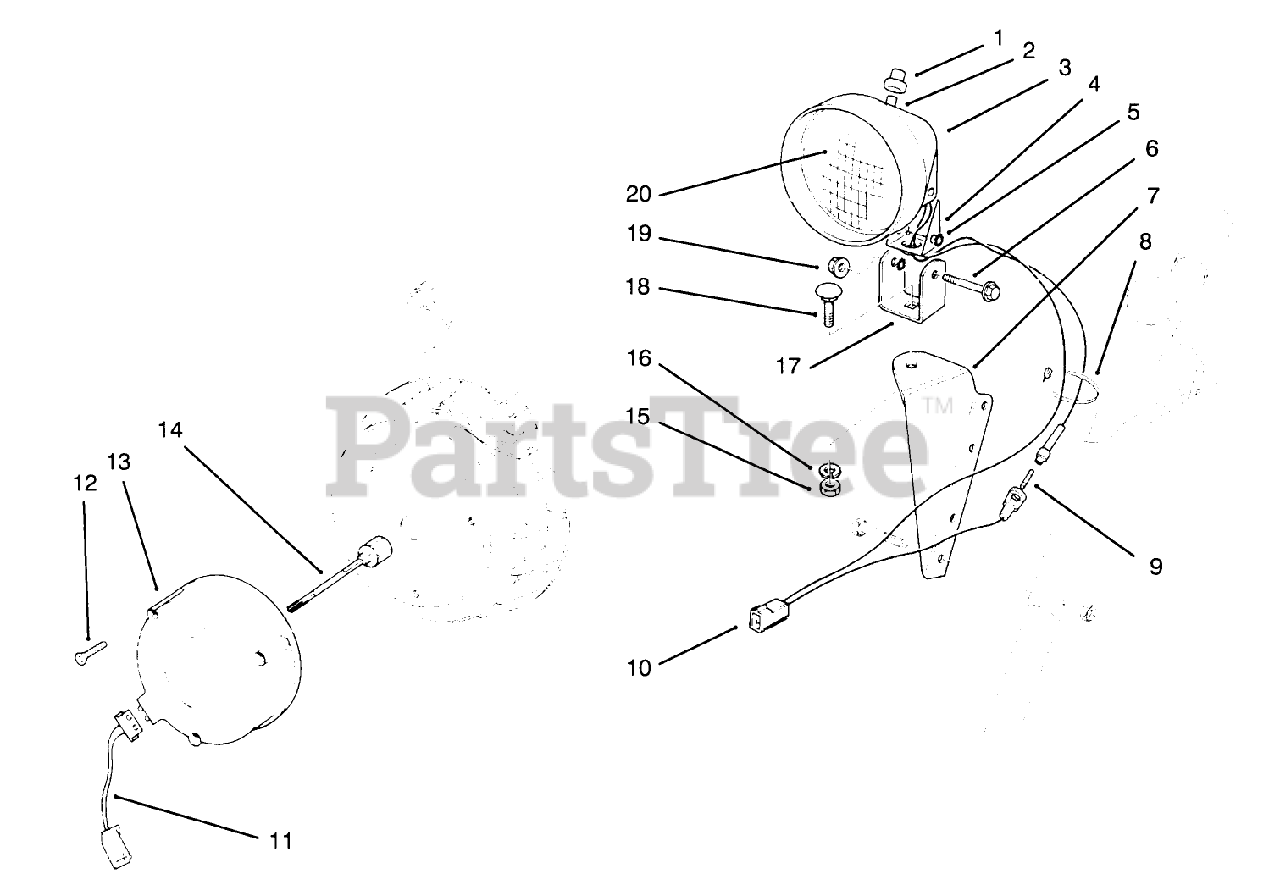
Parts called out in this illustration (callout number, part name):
2	SWITCH ASM
3	Bucket-Headlamp
4	TO BE DISCONTINED-NOT NEEDED ON PRODUCT
5	WASHER-LOCK
6	SCREW-HH
7	LAMP MOUNT B
8	TIE-CABLE
9	Fuse-7-1/2 Amp
10	WIRE ASM
11	Connector-Wire
12	SELF TAP SCREW
12	SELF TAPPING SCREW
13	Alternator
14	Shaft-Alternator 4
15	NUT-HEX
16	WASHER-LOCK
17	BRACKET
18	BOLT-CARR
19	NUT-HF
20	BEAM-SEALED
